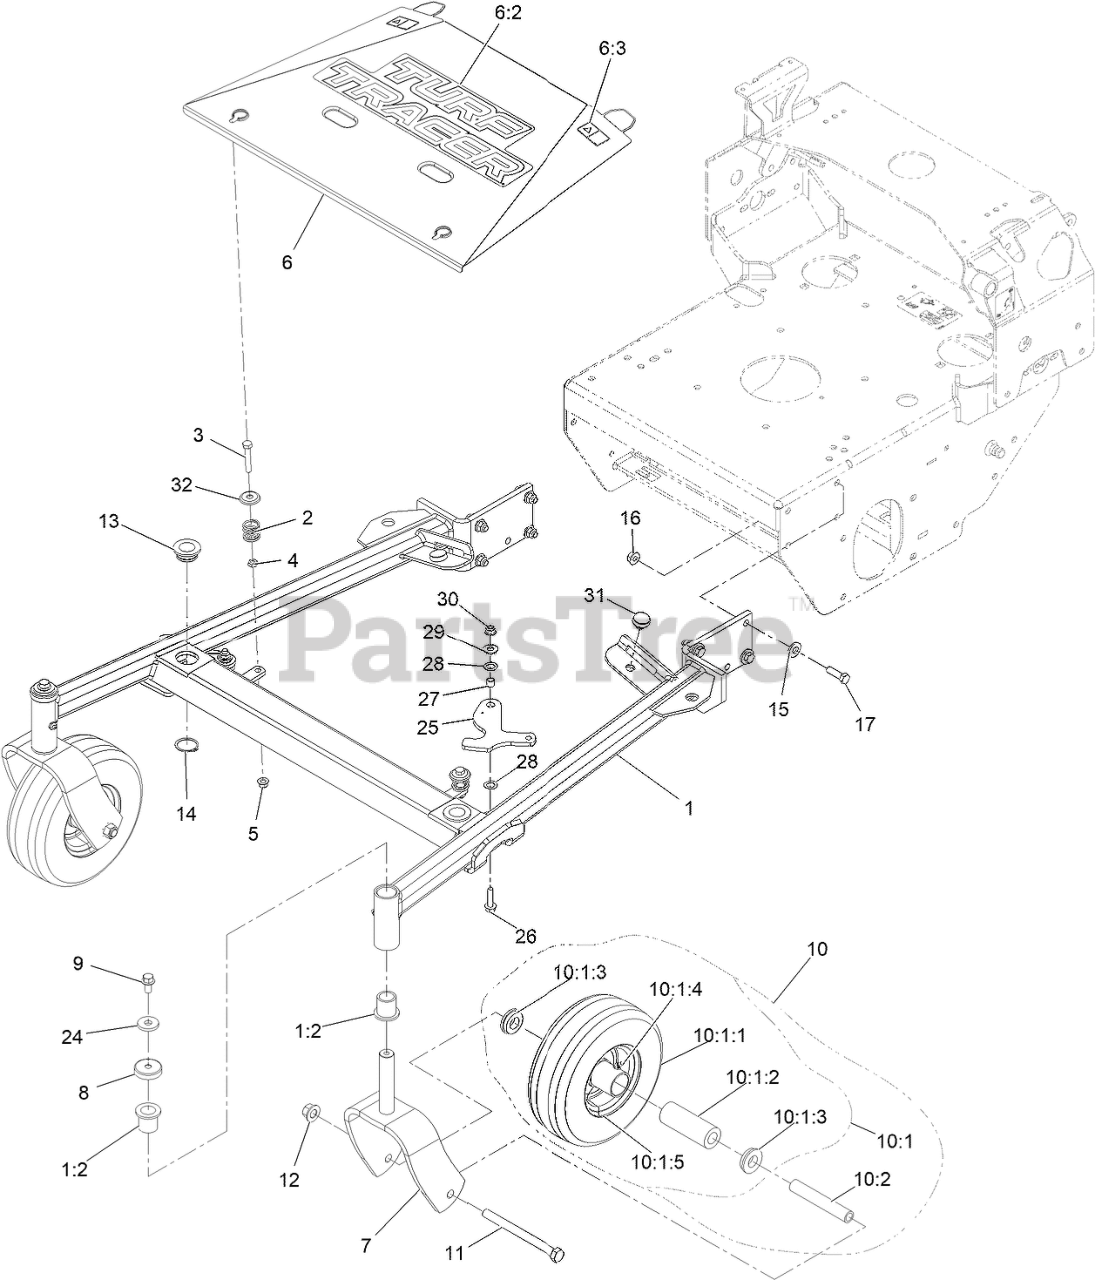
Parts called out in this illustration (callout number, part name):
1	ASM-48" Tts Front Frame
1:2	BEARING-FLANGED
3	SCREW-HH
4	NUT-JAM
5	NUT-HF, NI
6	ASM-48" Tts Center Shield
6:2	DECAL-TURF TRACER
6:3	DECAL-WARNING
7	FORK, CASTER
8	CAP, DUST
9	SCREW-HHF
10	KIT, SP CASTER WHEEL REPLACEMENT
10:1	Wheel And Tire ASM
10:1:1	Tire
10:1:2	BEARING
10:1:3	BUSHING
10:1:4	FITTING-GREASE
10:1:5	Wheel
11	SCREW-HH
12	Nut-Lock 1/2-13
13	BUSHING-DECK
14	RING-RETAINING
15	WASHER-BELLEVILLE
16	NUT-HF, NI
17	SCREW-HH
25	LATCH, DECK HEIGHT
26	Screw-HHF
27	Spacer-Grommet
28	WASHER-CONICAL
29	WASHER-FLAT
30	NUT-HF, NI
31	BUMPER-RUBBER
32	Washer-Cup
